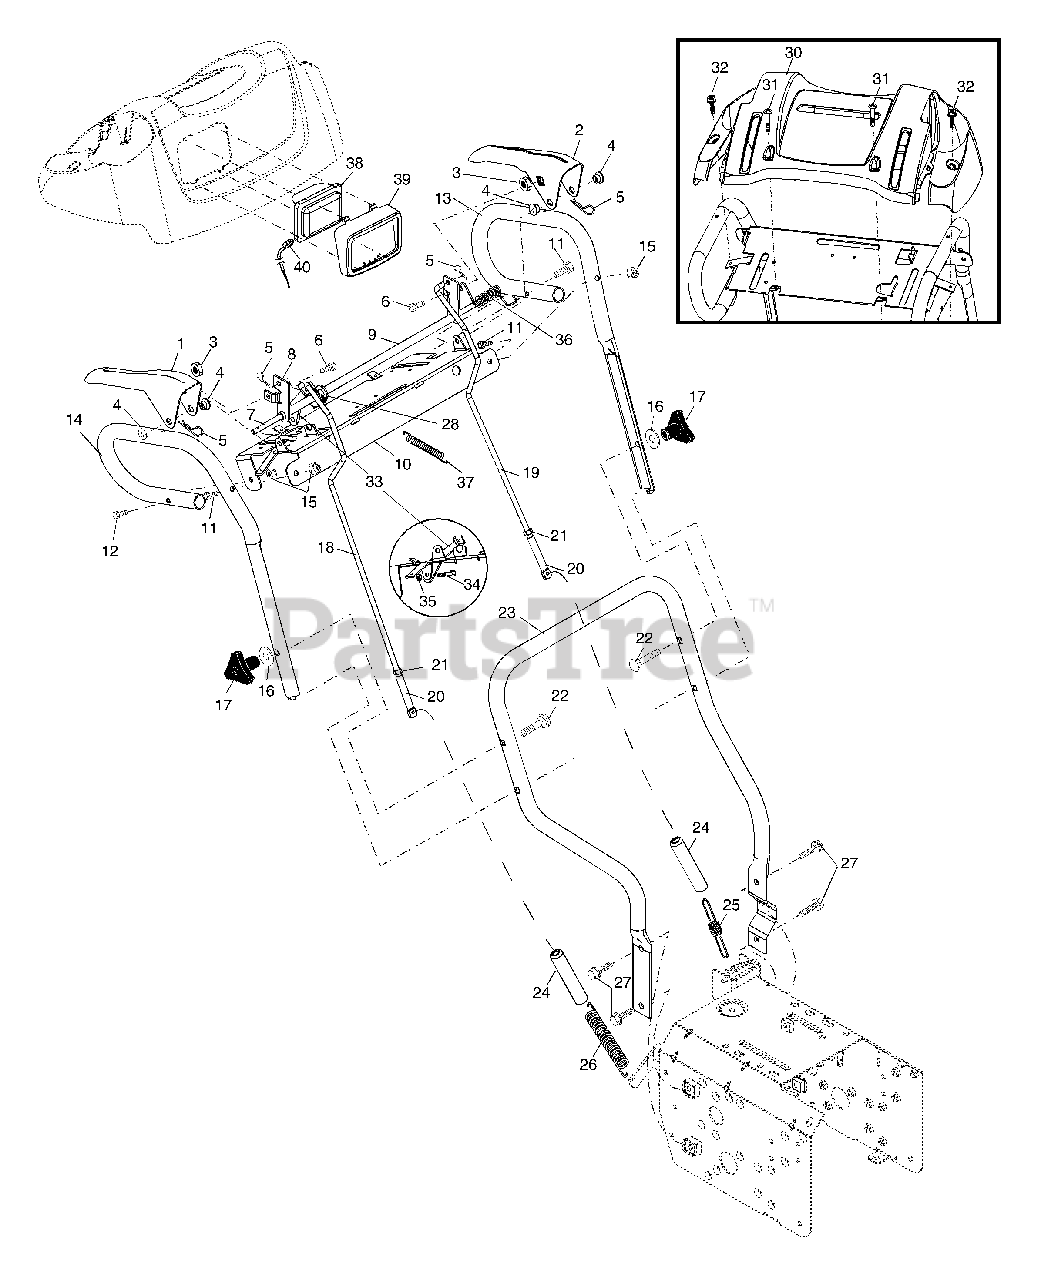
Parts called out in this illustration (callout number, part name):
1	Lever, Auger Control, RH
2	Lever, Traction Drive Control, LH
3	Nut, Cage 1/4-20
4	Bushing, Flange
5	Retainer, Hairpin
6	Screw, Hex Head 1/4-20 x 3/4
7	Rod, Interlock
8	Tube Assembly, Interlock, RH
9	Tube Assembly, Interlock, LH
10	Panel, Control
11	Screw, Hex Head 5/16-18 x 1-1/2
12	Screw, Hex Head 5/16-18 x 1-3/4
13	Handle Tube, LH
14	Handle Tube, RH
15	Nut, Lock 5/16-18
16	Washer, Flat 3/8
17	Knob, Handle
18	Rod, Auger Control
19	Rod, Traction Control
20	End, Control Rod
21	Nut, Hex, Jam 5/16-18
22	Bolt, Carriage 3/8-16 x 2-1/4
23	Handle Tube, Lower
24	Sleeve, Spring
25	Spring, Traction Drive
26	Spring, Auger Control
27	Screw, Hex Head 3/8-16 x 1
28	Clip, Panel
30	Console, Panel
31	Screw, Hex Head, Tapping #10-24 x 1-1/4
32	Screw, Hex Head, Tapping #10-24 x 1/2
33	Latch, Interlock
34	Bolt, Shoulder
35	Nut, Lock 1/4-20
36	Spring, Torsion
37	Spring, Interlock
38	Headlight, Halogen
39	Bezel, Headlight
40	Harness, Headlight (Halogen)
